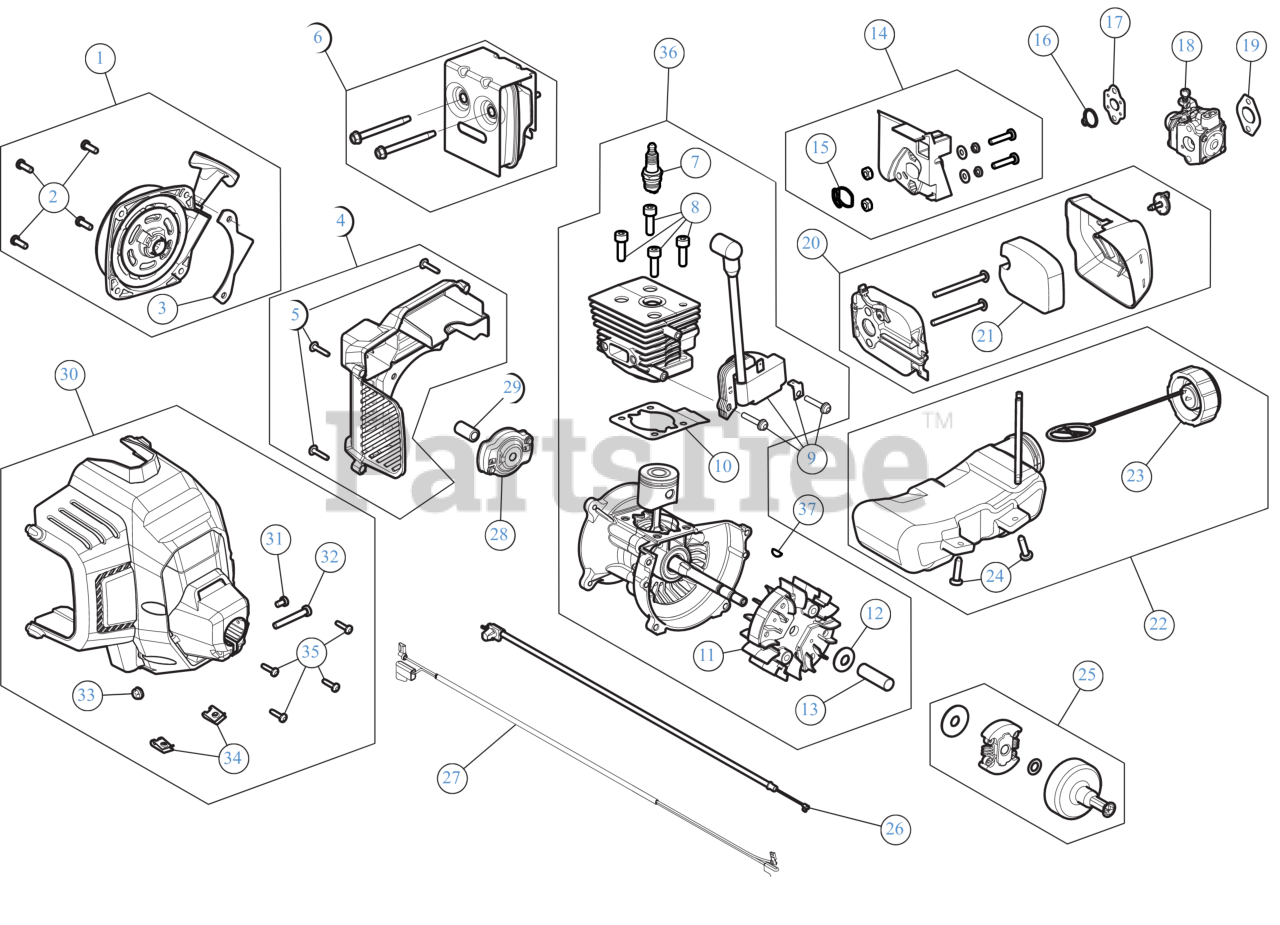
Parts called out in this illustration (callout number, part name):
1	STARTER ASSEMBLY
2	SCREW:10-32X.562:#8P
3	STARTER GUARD
4	REAR ENGINE COVER
5	SCREW 8-16 x 3/4
6	MUFFLER ASSEMBLY
7	SPARK PLUG
8	SCREW 1/4 x 20 x .8125
9	MODULE 27CC DIG
10	GASKET CYL
11	FLYWHEEL ASSEMBLY 27CC
12	BELL WASHER
13	SPACER
14	INTAKE ASSEMBLY
15	O-RING
16	O-RING
17	CARBURETOR GASKET
18	CARBURETOR
19	GASKET CARB
20	AIR CLEANER
21	AIR FILTER
22	FUEL TANK ASSEMBLY
23	FUEL CAP
24	SCREW:10-6 x .75
25	SMALL CLUTCH ASSEMBLY W/SMALL DRUM
26	THROTTLE CABLE
27	LEAD WIRES
28	PAWL ASSEMBLY AC5
29	ELECTRIC START ADP
30	CLUTCH COVER
31	SCREW, 8-32 x .312 P
32	SCREW
33	HEX NUT
34	NUT, TINNERMAN U-T
35	SCREW #
36	SHORTBLOCK
37	WOODRUFF KEY #403-.125 x .375
